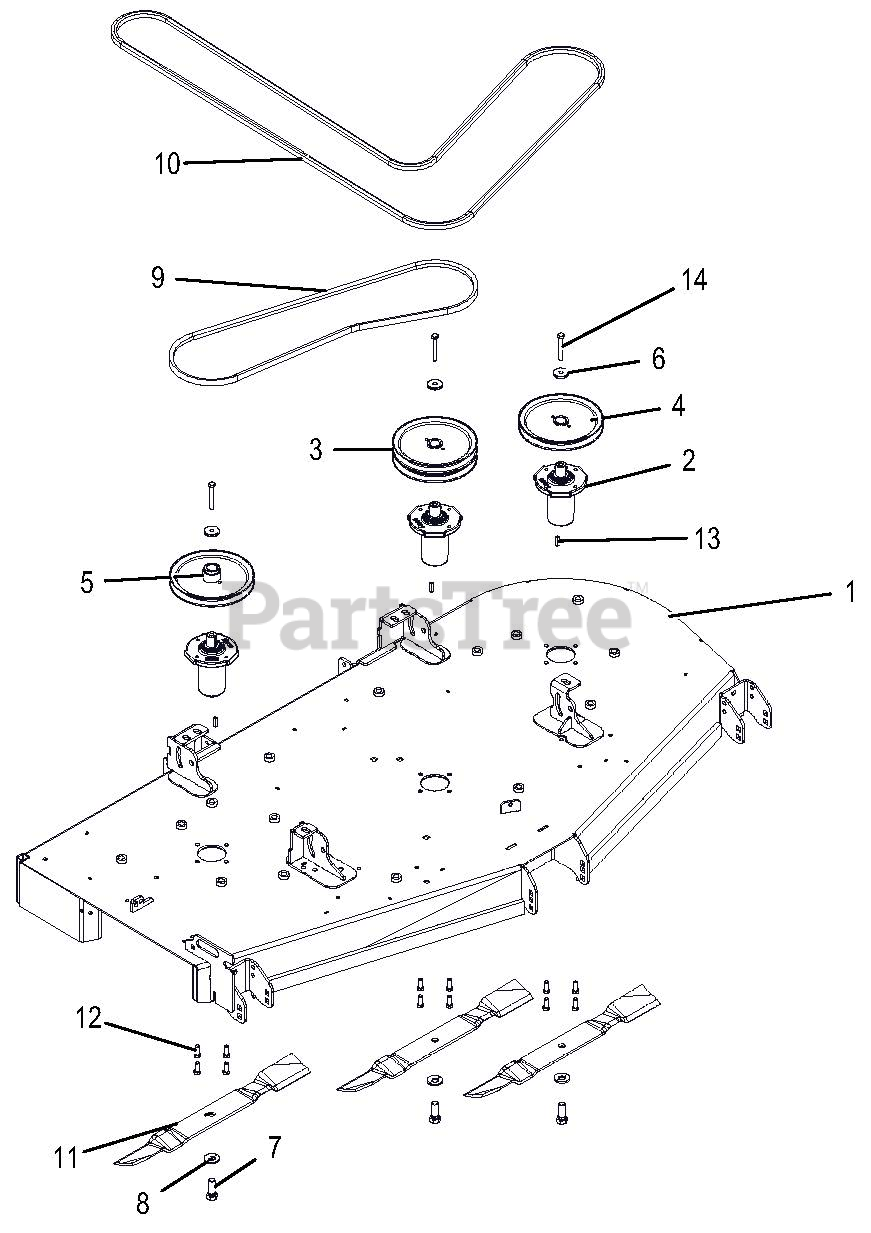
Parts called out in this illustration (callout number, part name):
1	WLDMT, DECK 72-CE
2	ASM, MAINT FREE SPINDLE
3	SHEAVE-DOUBLE 1.00"IDX8.25"OD
4	SHEAVE-SINGLE 1.00"IDX8.25"OD
5	SHV-SINGLE 1.00"ID X 8.25"OD
6	RETAINER, SHEAVE
7	BLT-HEX .62-18X1.75 GR8 YWZC
8	WSHR-BLVL .669X1.535X.138
9	V-BELT, B-COGGED
10	HEX BELT, BB WRAPPED
11	BLADE,MOWER-72"MULCH(24.5"LG)
12	BLT-HEX .38-16X1.0 GR8 YZ EP30
13	KEY, SQ .25X.25X1.00 RC 40-50
14	BLT-HEX .38-16X2.75 GR8 YWZC
